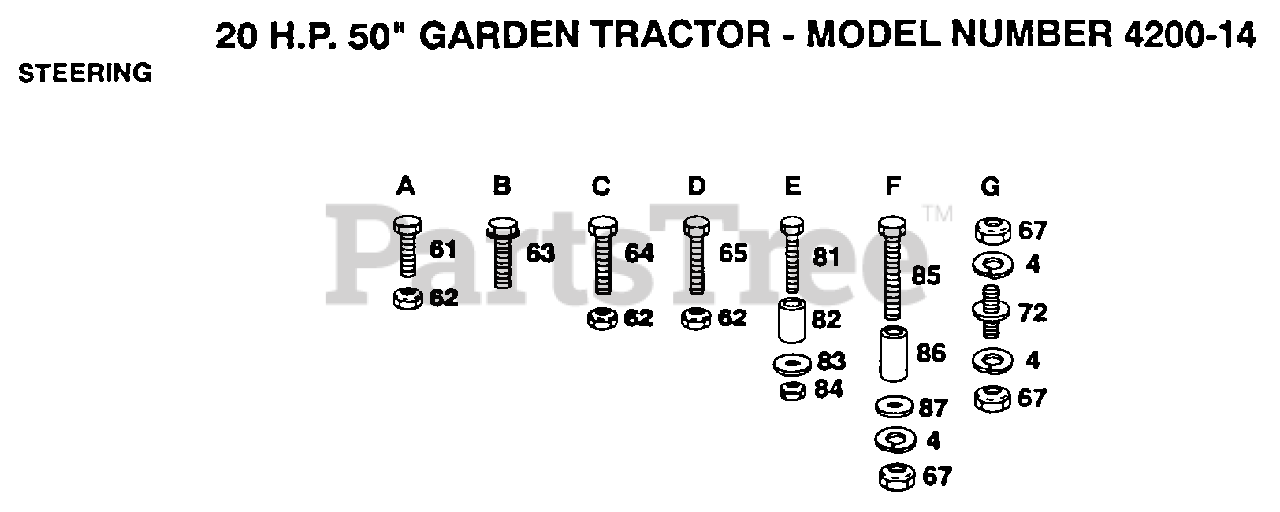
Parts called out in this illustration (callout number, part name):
4	LOCKWASHER
63	SCREW
64	BOLT
65	BOLT
67	NUT.HEX.3/8-16UNC
82	SPLIT SPACER YTV
83	WASHER
85	BOLT
86	BUSHING LT
87	WASHER
